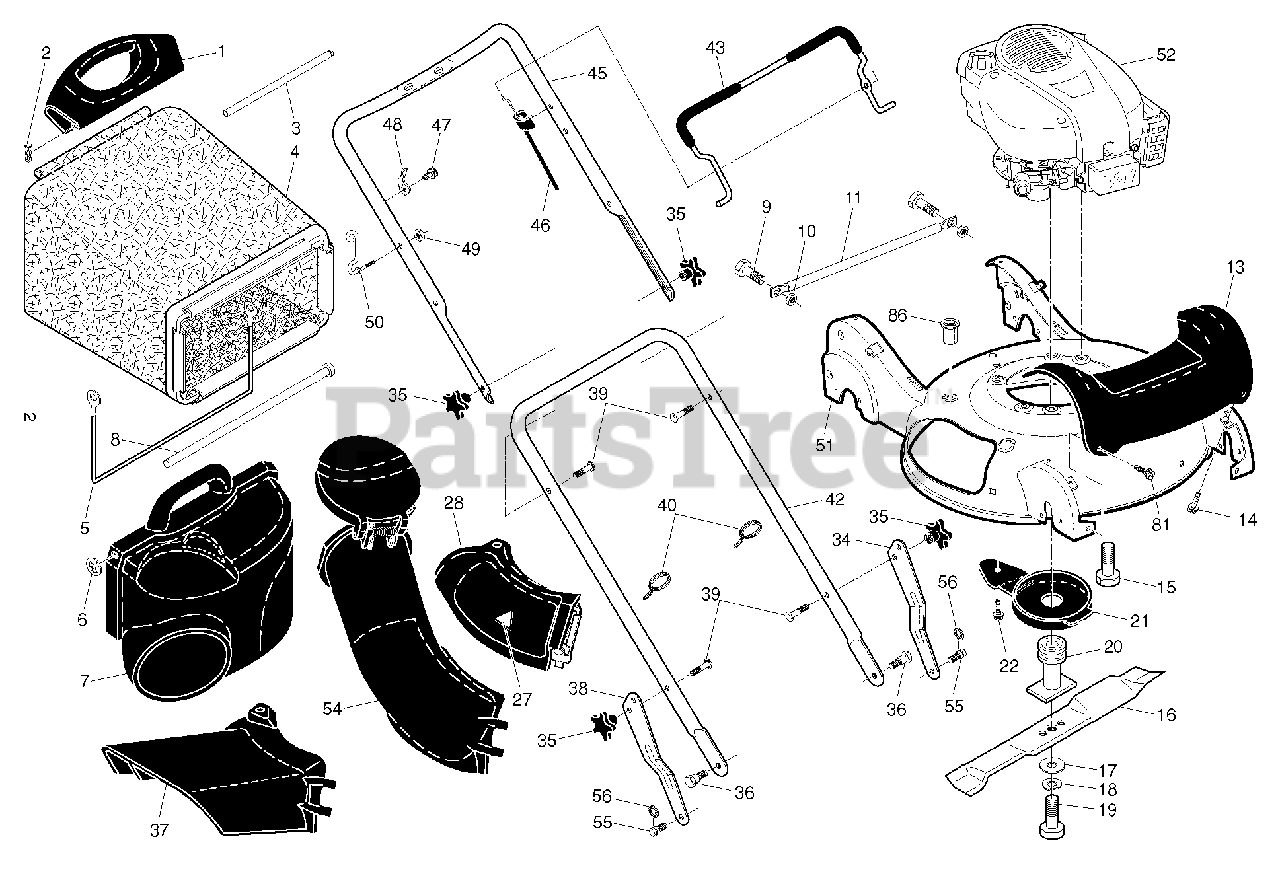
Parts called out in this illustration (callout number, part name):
1	HANDLE.GRASSBAG.REAR.H-GRAY
2	COTTER PIN (3 2)(2 2MC)
3	ROD.REAR.HANDLE.YELLOW
5	FRAME, GRASSBAG
7	DOOR, GRASSBAG
8	ROD, PIVOT
10	LOCKNUT.NYLOC.1/4-20
11	TUBE, REAR SKIRT
13	COVER.FRONT.21.HV.H-GRAY
14	SCREW, HEX WASHER HEAD
15	BOLT 3/8-16X1-1/8
16	Blade, 21"
17	WASHER,HARDEN
18	LOCKWASHER
19	BOLT.HD.HEAD.3/8-24X2.50
20	ADAPTER.BLADE
21	DEBRIS SHEILD
22	SCREW 1/4X20
27	DECAL.INTERNATIONL.CUTFINGER
34	ADJUSTMENT BRACKET, LOWER LH
35	KNOB.HANDLE.PLASTIC.STAR.BLACK
36	SCREW.5/16X.680.TRIM.H
38	BRACKET.ADJ.LOWER.HDL.RT.GREY
39	BOLT, HANDLE 5/16-18X1.75
40	TIE GUIDE
42	HANDLE.LOWER.GREY
43	BAIL.OVER.MOLD.ERGO.MZR.ORANGE
45	HANDLE.UPPER.3.POS.BS.AW2.GREY
46	CABLE.MZR.50.SNAP-IN
48	BRACKET.UPSTOP.RT
49	NUT
50	GUIDE.ROPE.WALK.MOWER
55	STUD.SHOULDER.T45.BZP
56	E-RING 7/16 RE
81	SCREW.HWH.13-16-5.8.BZP
